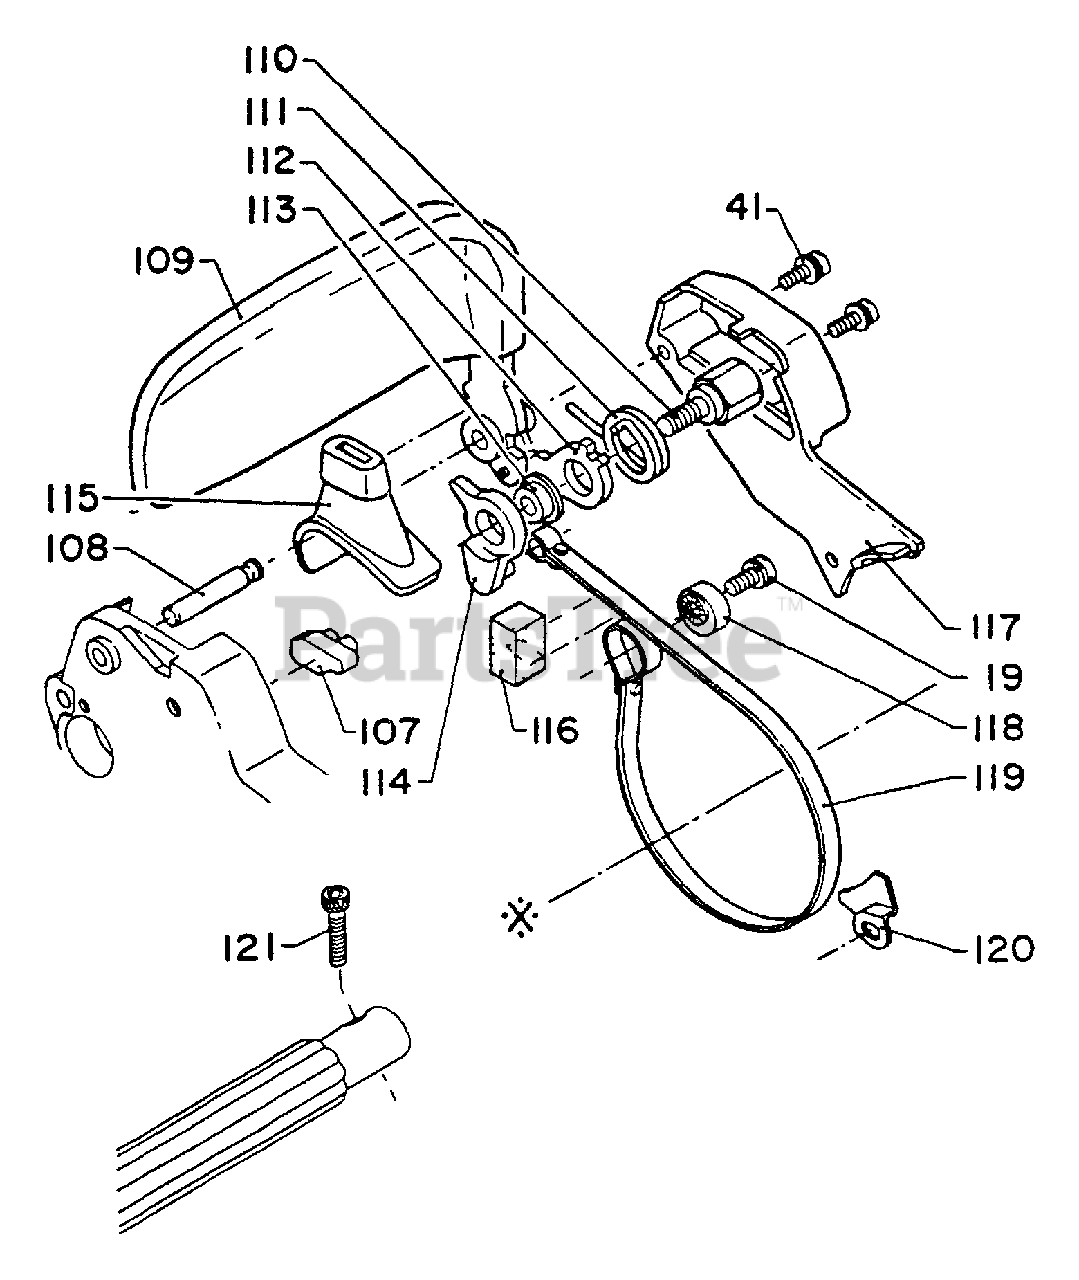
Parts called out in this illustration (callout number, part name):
19	SCREW - 5X10
41	SCREW - 4X10
107	RESET, BRAKE
109	HANDLE, BRAKE
111	SPRING, RETURN
114	CONNECTOR
115	COVER, BRAKE
116	SEAL
117	COVER, BRAKE
118	ADJUSTER, BRAKE BAND
119	BAND, BRAKE
120	RETAINER, BRAKE BAND
121	SCREW - 5X25
